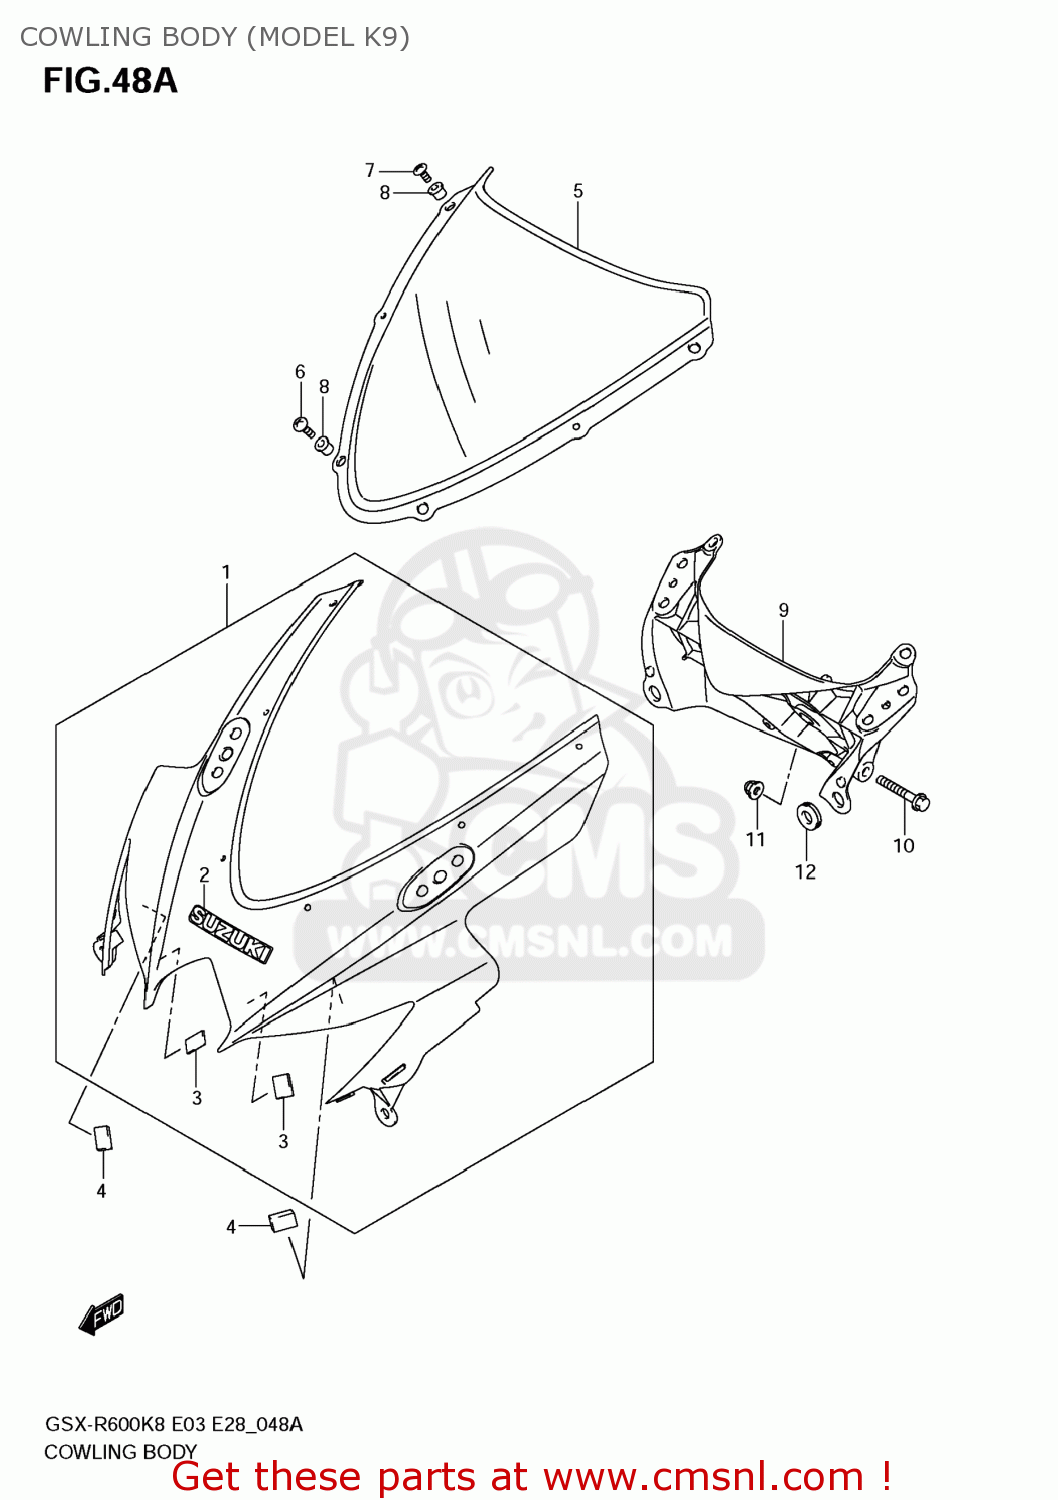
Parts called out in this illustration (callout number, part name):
1	BODY ASSY,COWLING
2	EMBLEM(GRAY)
3	FASTENER,COWLING
4	CUSHION,BODY COWLING
5	WINDSCREEN
6	SCREW(5X18)
7	SCREW(5X15)
8	NUT
9	BRACE,COWLING
10	BOLT
11	NUT
12	CUSHION
